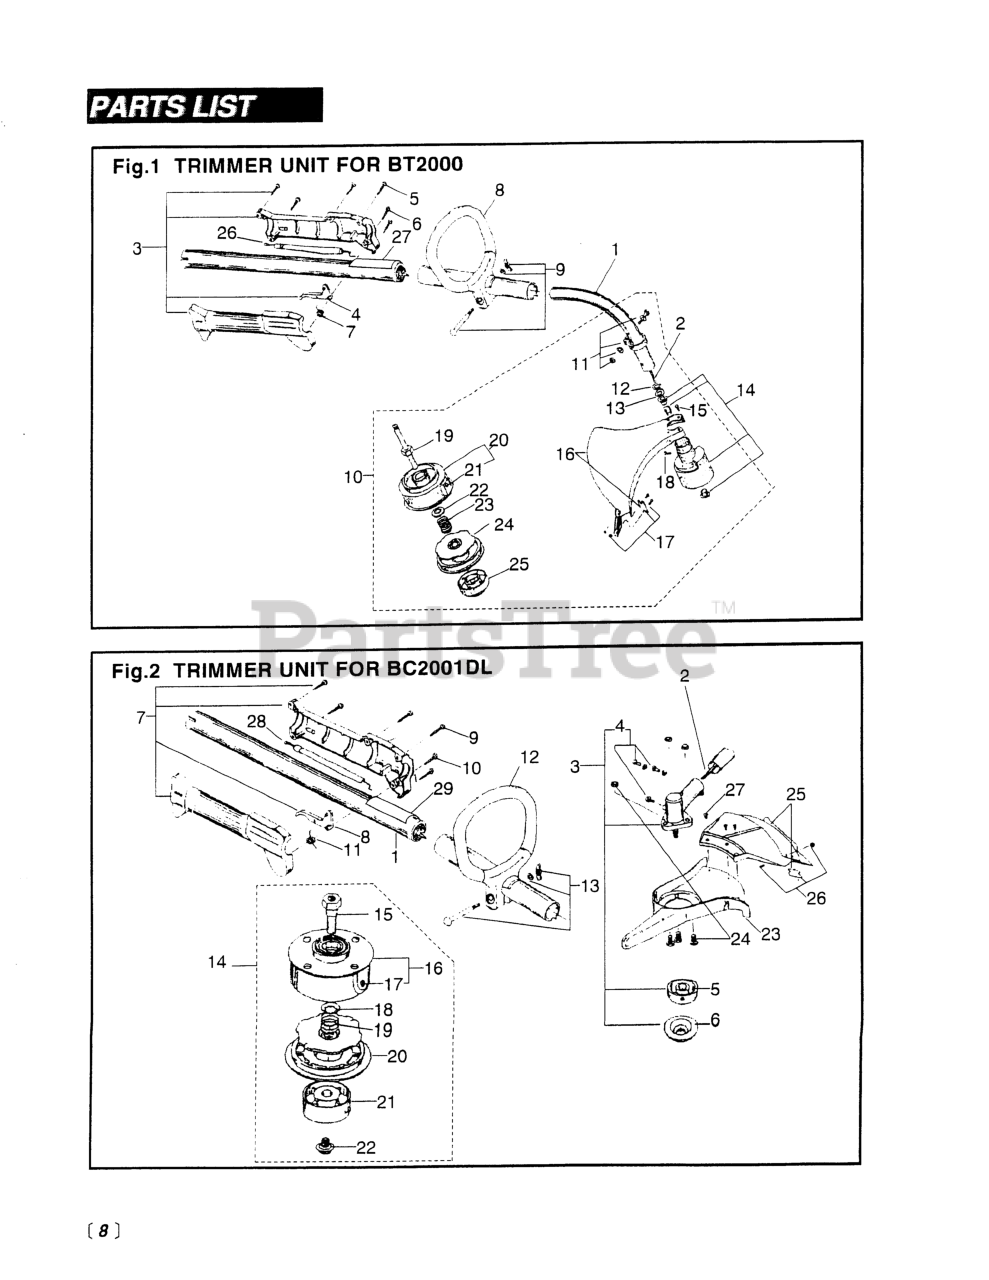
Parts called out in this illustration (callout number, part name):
1	PIPE ASSY (BC2001)(NLA)
2	SHAFT, FLEX (RLPS. 181773)
3	GEARCASE ASSEMBLY
4	HARDWARE, MOUNTING
5	HOLDER (U), BLADE DRIVER
6	HOLDER (L) (RPLS 613222)
8	LEVER, THROTTLE
9	SET SCREW, ANTI-ROTATION
11	SPRING, THROTTLE TRIGGER
14	UBT200 - CUTTING HEAD ASSY.
15	SHAFT
16	HOUSING, OUTER SPOOL
17	EYELET
18	WASHER
19	SPRING, INNER REEL
20	REEL, INNER
21	KNOB (USE 180814)
22	KNOB, BUMP HEAD (USE 180814)
23	MOUNT, GUARD
24	GUARD MOUNT HDWE SET
25	GUARD ASSEMBLY
26	BLADE ASSEMBLY
27	SCREW, GUARD MOUNT ASSY
28	CABLE COMP (RPLS 6460- )
29	LABEL, BC2001DL
